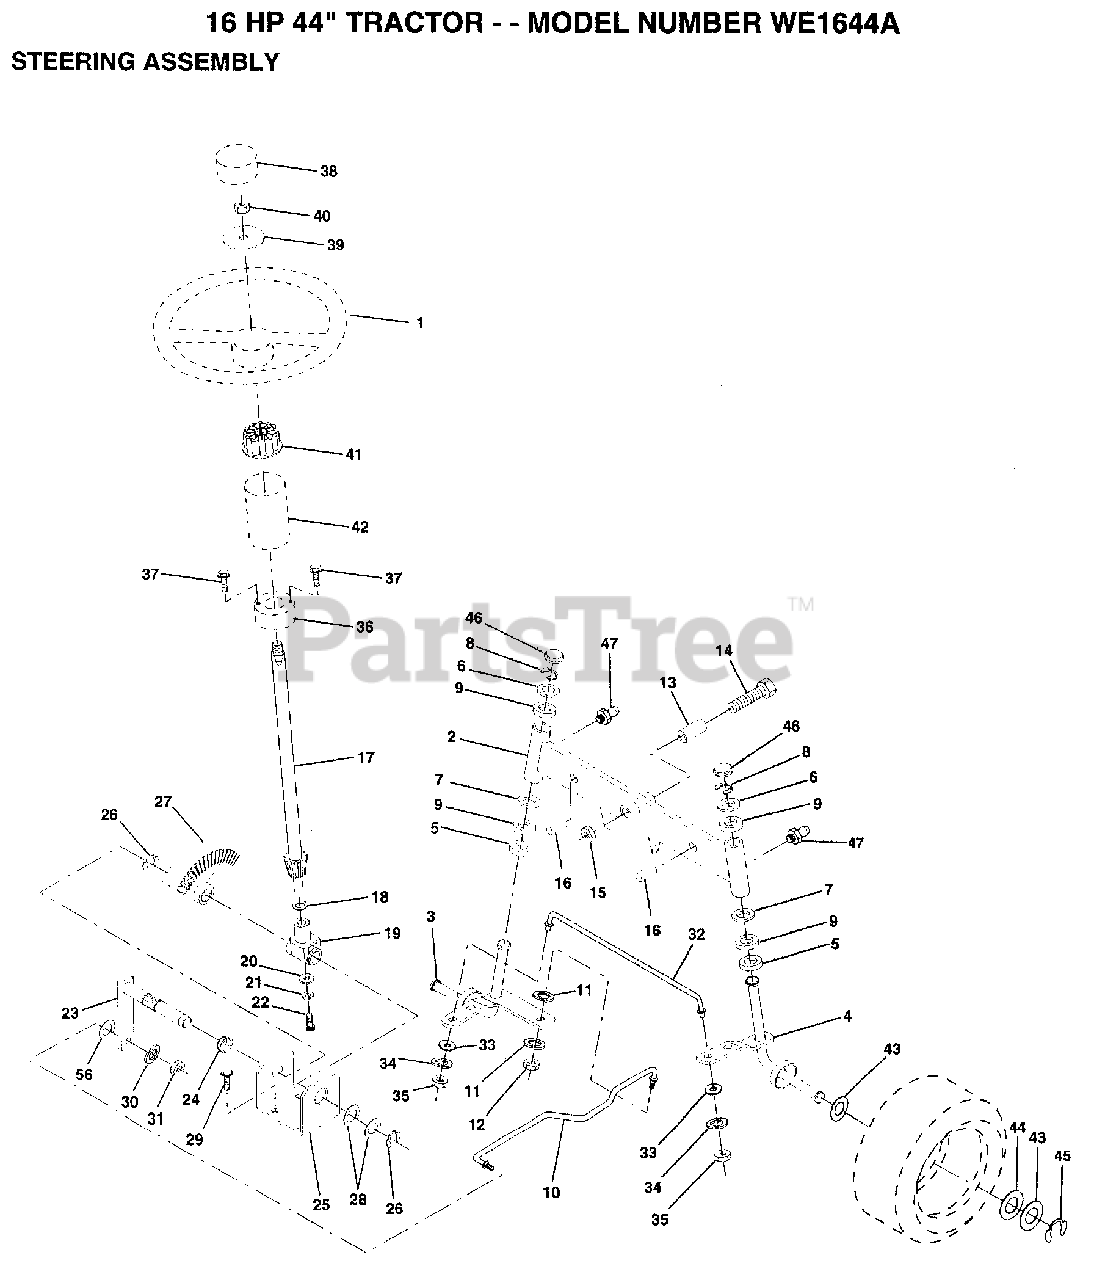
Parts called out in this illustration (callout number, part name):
1	ST WHL INSERT CAP
2	AXLE ASM FRONT
5	WASHER .T
6	WASHER
7	WASHER
8	RING
9	COL. SRTG. BEAR.
11	LOCKWASHER
13	BEARING
14	BOLT LT
15	"NUT-LOC,FLANGE LT"
16	AXLE PIN
17	SHAFT&GEAR STR T
18	THRUST WASHER
19	SUPPORT.SHAFT
21	LOCKWASHER
22	"SCREW,SPECIAL"
24	NYLINER T
25	"BRKT,STEERING"
26	RING
27	GEAR SECTOR
28	WASHER .T
29	SCREW
30	LOCKWASHER
32	TIE ROD
33	WASHER M
34	LOCKWASHER
35	NUT.LOCK.5/16-24
38	ST WHL INSERT CAP
39	WASHER
41	ADAPTER LT
43	WASHER
44	WASHER
45	RING
46	CAP
47	ZERK M
56	WASHER
